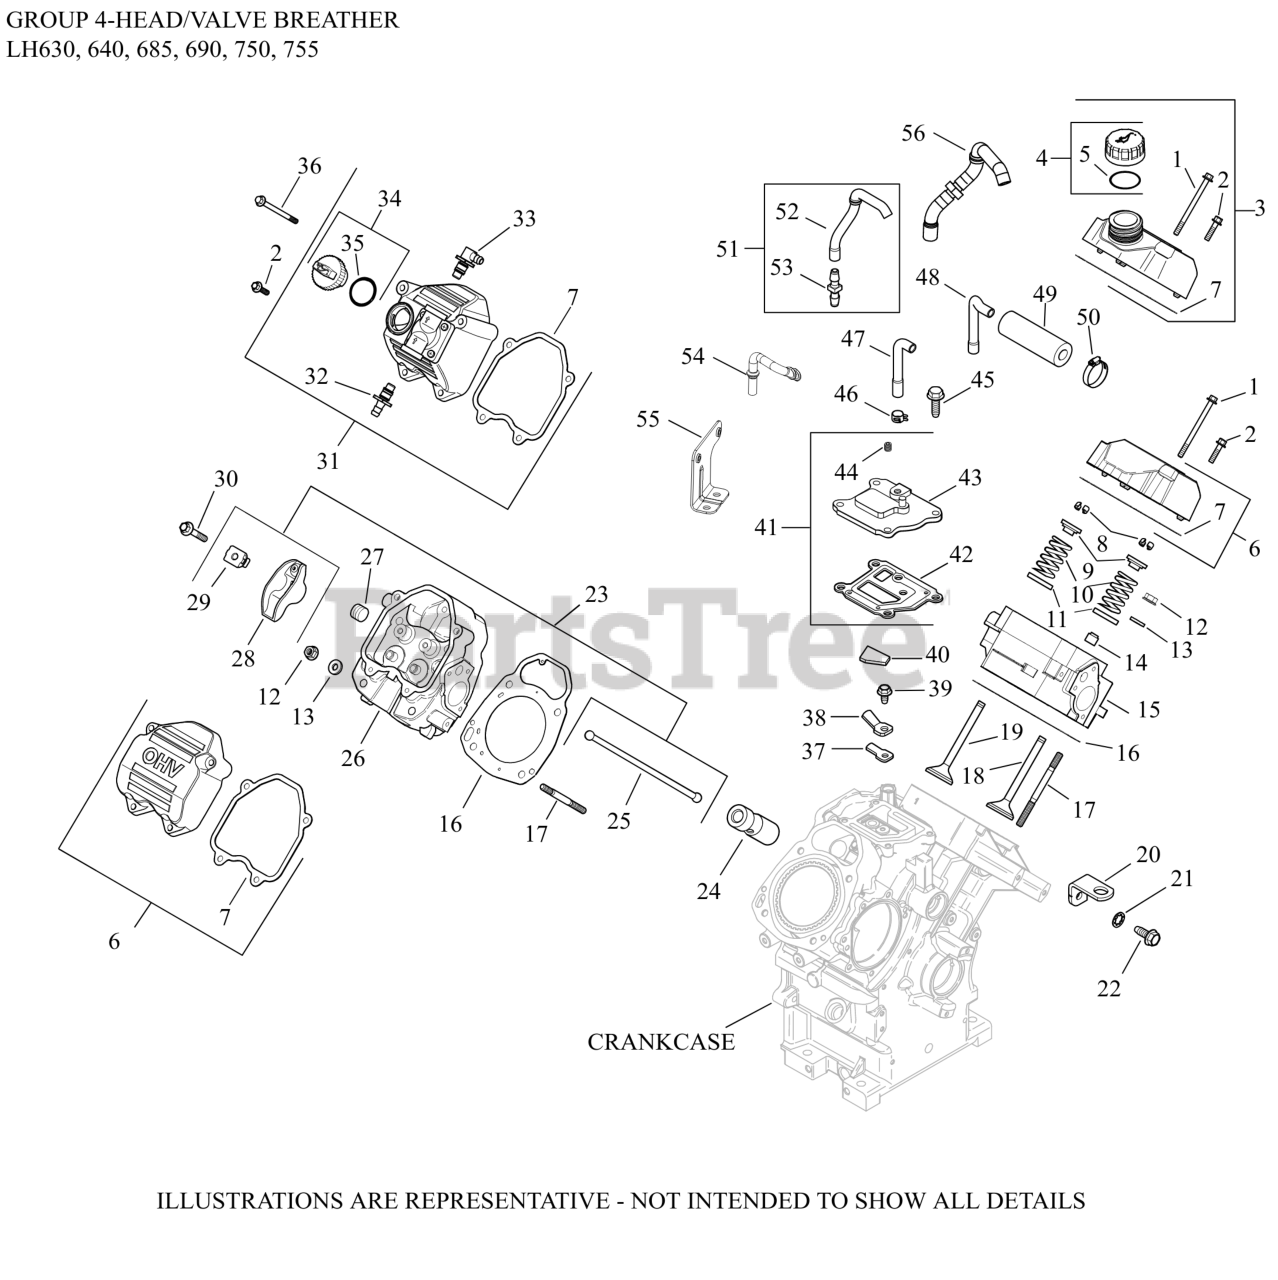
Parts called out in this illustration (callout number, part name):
1	SCREW, FLG M6X1.0X80
2	SCREW, FLG M6X1.0X25
6	KIT, ROCKER COVER
7	GASKET, VALVE COVER
8	KIT, RETAINER
9	RETAINER, VALVE SPRING - USE 25 173 28-S
10	SPRING, VALVE
11	RETAINER-USE 235011-S
12	NUT, FLG M8X1.25
13	WASHER, FLAT 5/16"
14	SEAL, VALVE STEM-USE 25 032 14-S
15	KIT, CYLINDER HEAD (#1 SIDE)
16	KIT,CYL HD GASKET #2SIDE-USE 66 841 04-S
18	VALVE, INTAKE (STD)
18	VALVE, INTAKE (.25)
19	VALVE, EXHAUST (STD)-USE 32 016 01-S
19	VALVE, EXHAUST (.25)
21	WASHER, INT TOOTH LOCK 1/4"
23	KIT, VALVE TRAIN
24	LIFTER, HYDRAULIC VALVE-USE 25 351 10-S
25	ROD, PUSH
26	KIT, CYLINDER HEAD (#2 SIDE)
27	PLUG, PIPE
28	ARM, ROCKER
29	PIVOT, ROCKER ARM
30	SCREW, ROCKER ARM PIVOT-USE M-640034-S
31	KIT, FUEL PUMP/ROCKER COVER
32	KIT, STRAIGHT FITTING
33	KIT, 90 DEG. FITTING
34	CAP ASSY, OIL FILL (YELLOW)
36	SCREW, FLG M6X1.0X55
37	REED, BREATHER-(#2440206S)
37	REED, BREATHER
38	RETAINER, REED
39	SCREW, FLG THD FRM M5X.8X10
40	FILTER, BREATHER
41	KIT, BREATHER ASSEMBLY
42	GASKET USE 24 041 51-S
42	GASKET, BREATHER-USE 24 041 67-S
45	SCREW,FLG THD FRM M6X1.0X20-(#25086396S)
46	CLAMP, BAND SPRING HOSE-(#2523737S)
47	HOSE, BREATHER
50	CLAMP, HOSE (KM)-USE 25 237 31-S
50	CLAMP, HOSE
